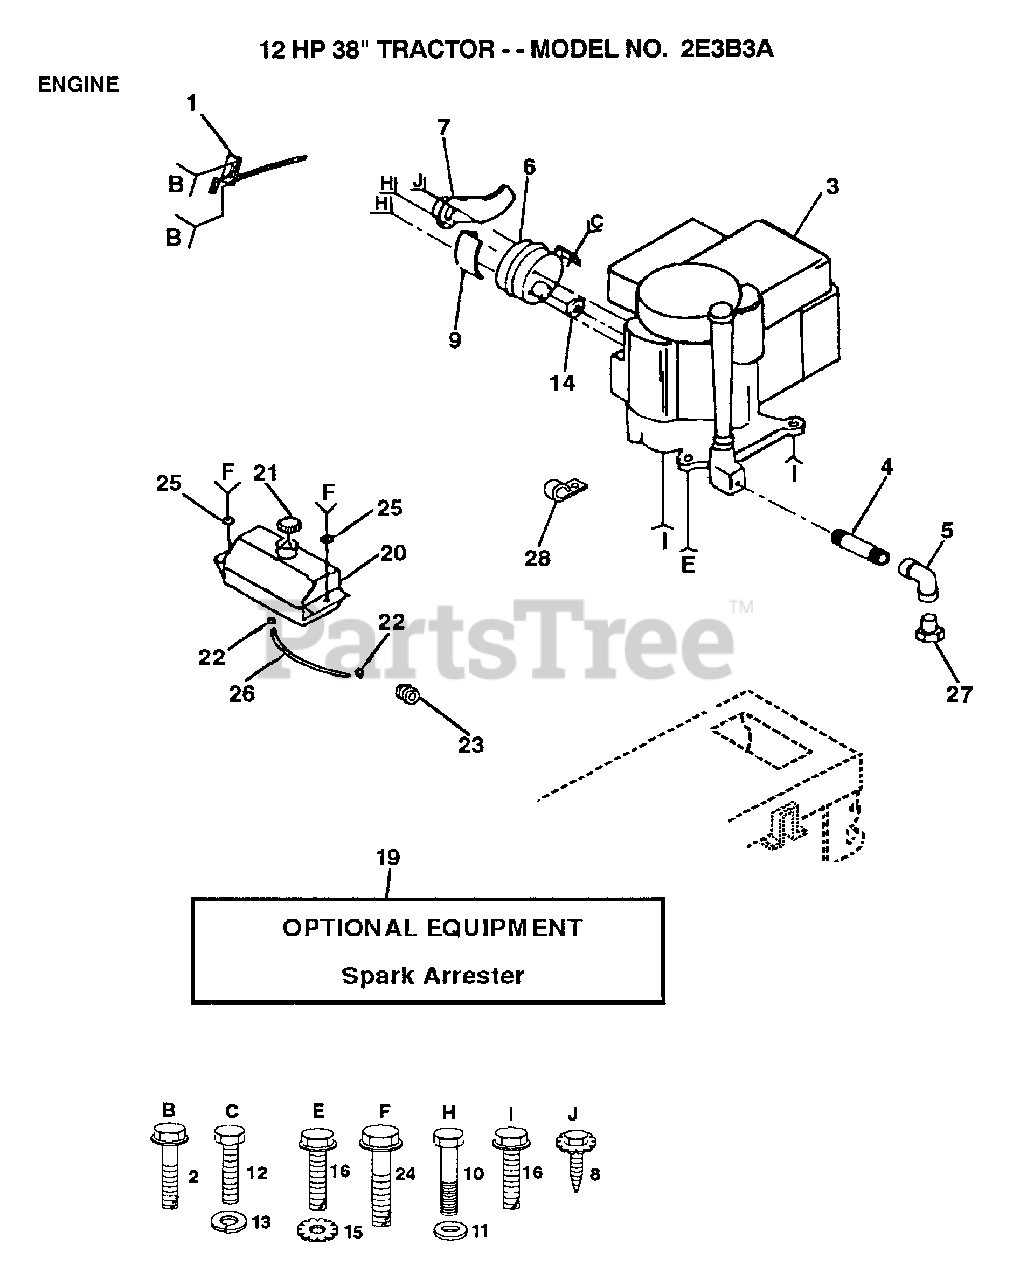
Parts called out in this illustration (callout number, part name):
1	THROTTLE CONTROL
2	SCREW LT
4	PIPE NIPPLE
5	ELBOW
6	MUFFLER LTV
7	DEFLECTOR MUFFLER
9	SHIELD HEAT LTV
10	"BOLT,HEX"
11	WASHER T
12	BOLT
13	LOCKWASHER
15	LOCKWASHER
16	SCREW
20	TANK.FUEL.LT.
22	HOSE CLAMP
24	SCREW
25	WASHER GT
26	FUEL LINE T
28	CLIP T
